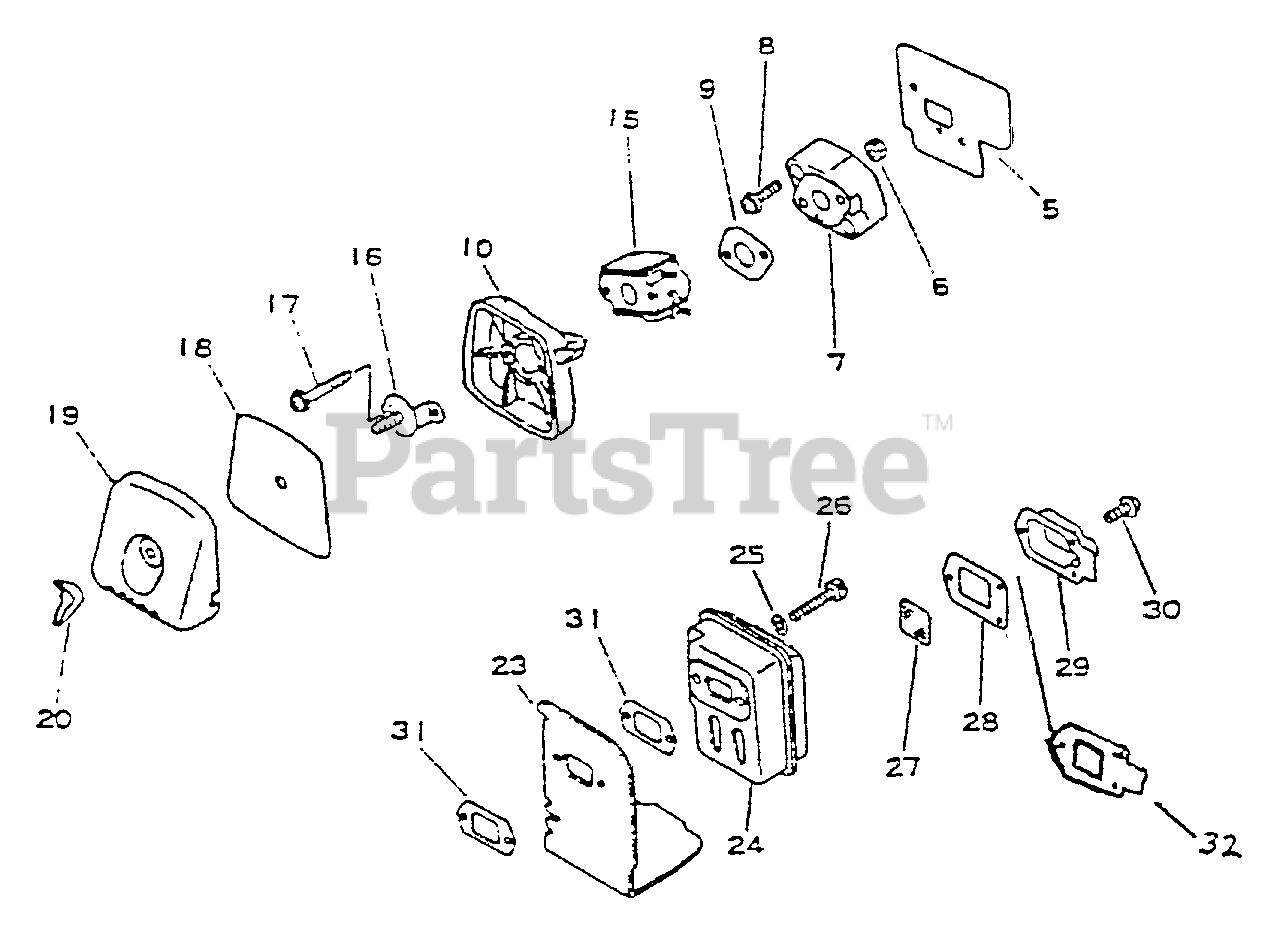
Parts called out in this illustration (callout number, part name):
5	GASKET, INTAKE
6	NUT M5
7	INSULATOR, INTAKE
8	SCREW 5×22
9	GASKET, INTAKE
10	AIR FILTER CASE ASSY
15	CARBURETOR
16	PLATE, PREVENT
17	SCREW 5×64
18	FILTER, AIR
19	COVER, AIR FILTER
20	WINGNUT - 5
23	COVER, MUFFLER
24	MUFFLER
25	WASHER, FLAT 5.5×10×0.8
26	BOLT 5×55
27	SCREEN, SPARK ARRESTER
28	GASKET, EXHAUST
29	GUIDE, EXHAUST - INNER
30	SCREW 4×10
31	GASKET, EXHAUST
32	GUIDE, EXHAUST
